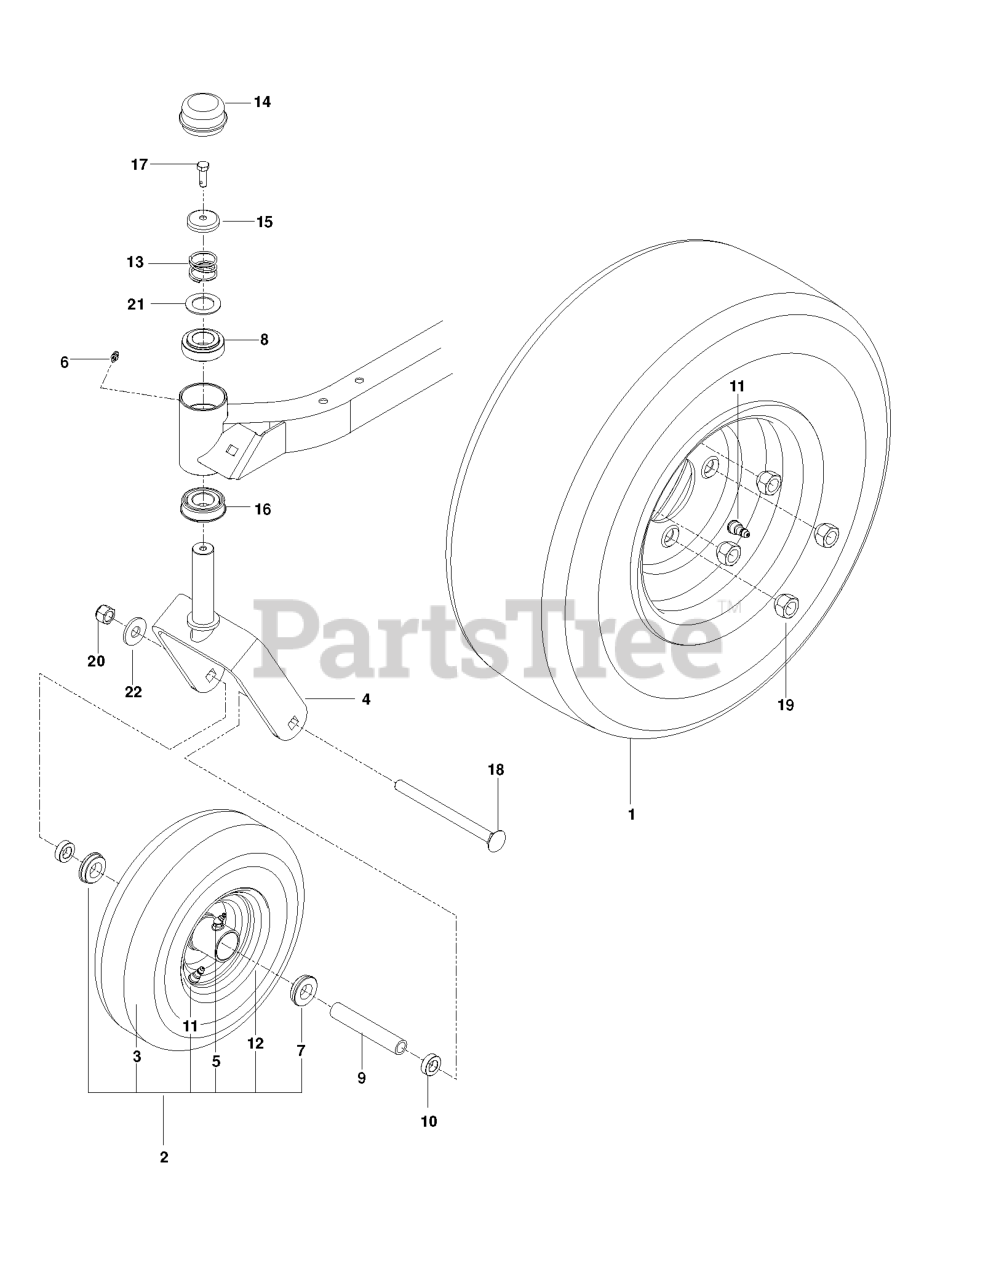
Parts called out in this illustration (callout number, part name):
1	REAR.WHEEL.TIRE.18X6.5X8.KENDA
2	TIRE.ASSEM.4.10-5.CASTER.GOLD
3	TIRE.11"X4"-5.4PLY.SMOOTH.KEND
4	YOKE.CASTER.ORANGE
5	ZERK
6	ZERK, 3/16, DRIVE IN
7	BUSHING, WHEEL, 3/4"
8	BUSHING, CASTER
10	SPACER, 5/16"
11	VALVE STEM TR-412
13	SPRING, CASTER
14	GREASE CAP
15	CASTER.PLUG
16	BEARING FLANGED
17	5/16-18X1 HHB G5W/NY
18	RHSNB 1/2-13 X 6.50 GR2 ZD
19	LUG NUT 1/2F
20	NUT 1/2-13 HEX CNTRLK GR 5 ZD
21	WASHER, 1.025 ID X 1.64
22	WASH USS FLAT 1/2
